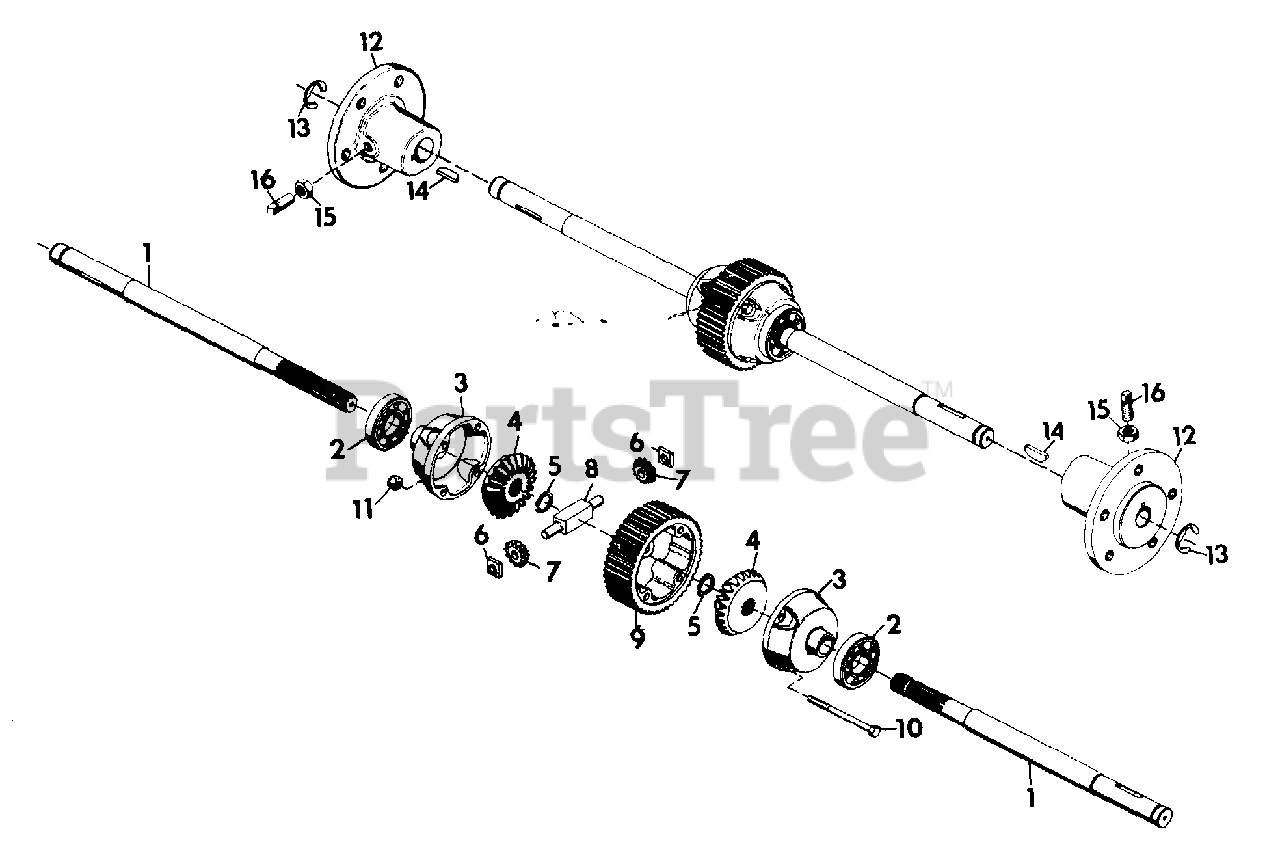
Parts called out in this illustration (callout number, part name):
1	AXLE, BEVEL GEAR DIFF.
2	BEARING, BALL 1.378X2.834X.669
3	CAP, DIFF. END
4	GEAR, BEVEL
5	RING, RETAINING 1.000 SHAFT
6	BLOCK, DRIVE
7	PINION, BEVEL
8	PIN, SPIDER PINION
9	GEAR, FINAL DRIVE
10	BOLT, HEX 5/16-18X2.5 GRADE-8
11	NUT, HEX 5/16-18 GRADE-8
12	HUB, WHEEL
13	E-RING 1.125 SHAFT
14	KEY, WOODRUFF .250X2.125 SOFT
15	NUT, JAM 3/8-16 HEX
16	SCREW, SET 3/8-16X1.25 SQ HD CUP PT.
